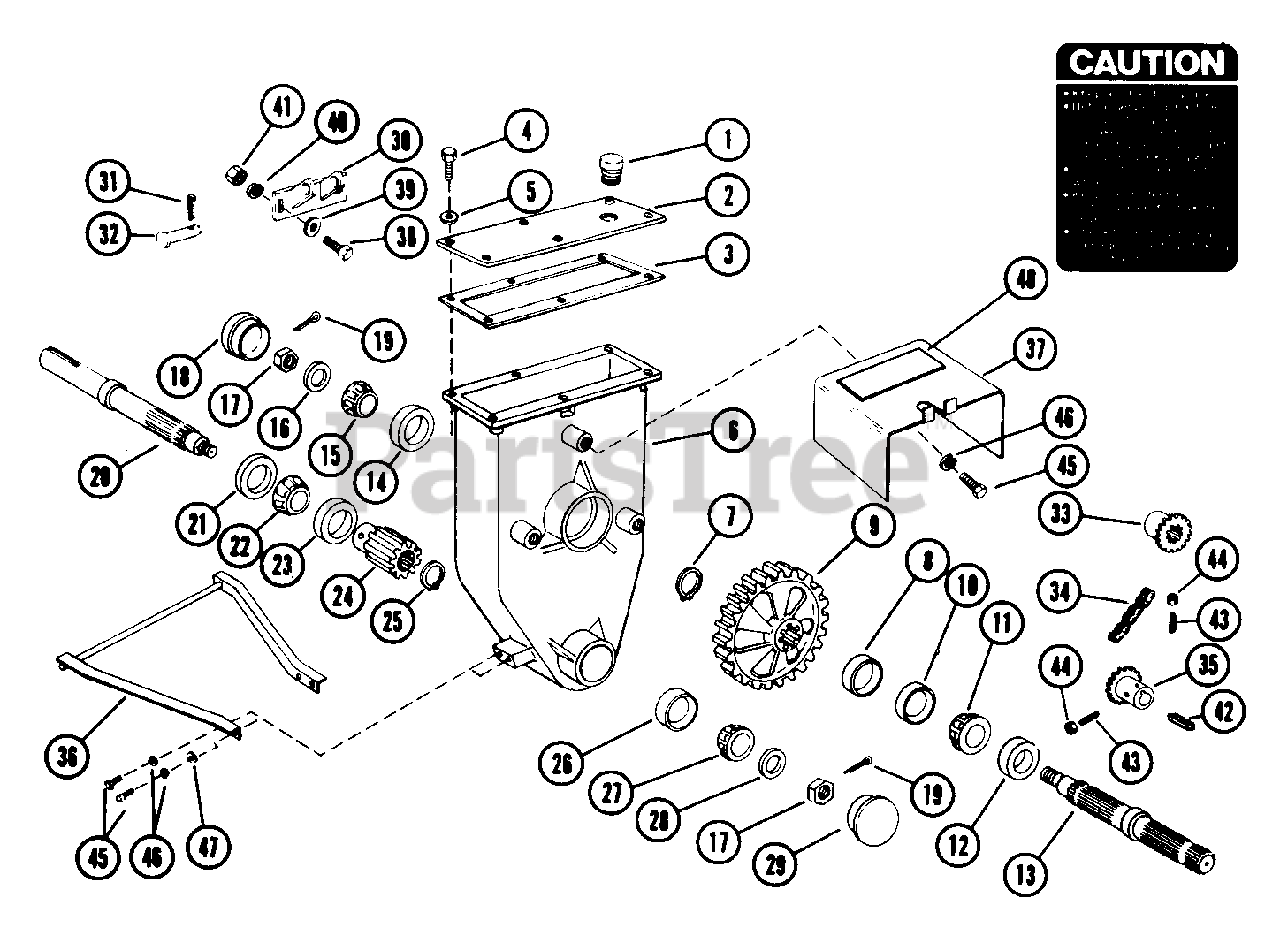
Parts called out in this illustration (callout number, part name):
1	AIR VENT
4	BLT-HEX .25-20X.50 PL GR2
5	WSHR-LK .250X.077 HVY PL
6	GEAR BOX
7	RG-RTNG-EXT 1.375X.050
8	SPACER 1.062X1.625X.375
10	BRG-CUP 2.563X.550
11	BRG-CONE 1.38X.72
12	SEAL 1.875X.625X.500
13	SHAFT ASSEMBLY
14	BRG-CUP1.980X.420
15	BRG-CONE 1.0X.58
16	WSHR-FL-STL .781X1.500X.188
17	NUT-JAM-SL .625-18
18	DUST CAP
19	PIN-COTR .12X1.0 PL
20	SHAFT ASSEMBLY
21	SEAL 1.500X2.265X.250
22	BRG-CONE 1.0X.81
23	BRG-CUP 2.441X.562
24	PINION GEAR
25	RG-RTNG-EXT 1.00X.042
26	BRG-CUP 1.781X.475
27	BRG-CONE .750X.61
28	WSHR-FL-STL.812X1.500X.139
31	PIN-HAIR INT .09X.188 PL
32	PIN-CLEV .619X2.0 YWZC
34	ROLLER CHAIN
35	SPROCKET
38	BLT-HEX .38-16X1.00 PL
39	WSHR-FL-STL .438X1.0X.083 PL
40	WSHR-LK .375X.094 MED PL
41	NUT-HEX .375-16
42	KEY-SQ .25 X 2.50 X .25 SAE
43	SCR-SET .32-18X.75 SQHCUP PL
44	NUT-JAM .312-18 PL
45	BLT-HEX .31-18X1.25 PL GR2
46	WSHR-LK .312X.097 PL HVY
47	WSHR-FL-STL .38X.875X.083 PL
48	DECAL CAUTION
